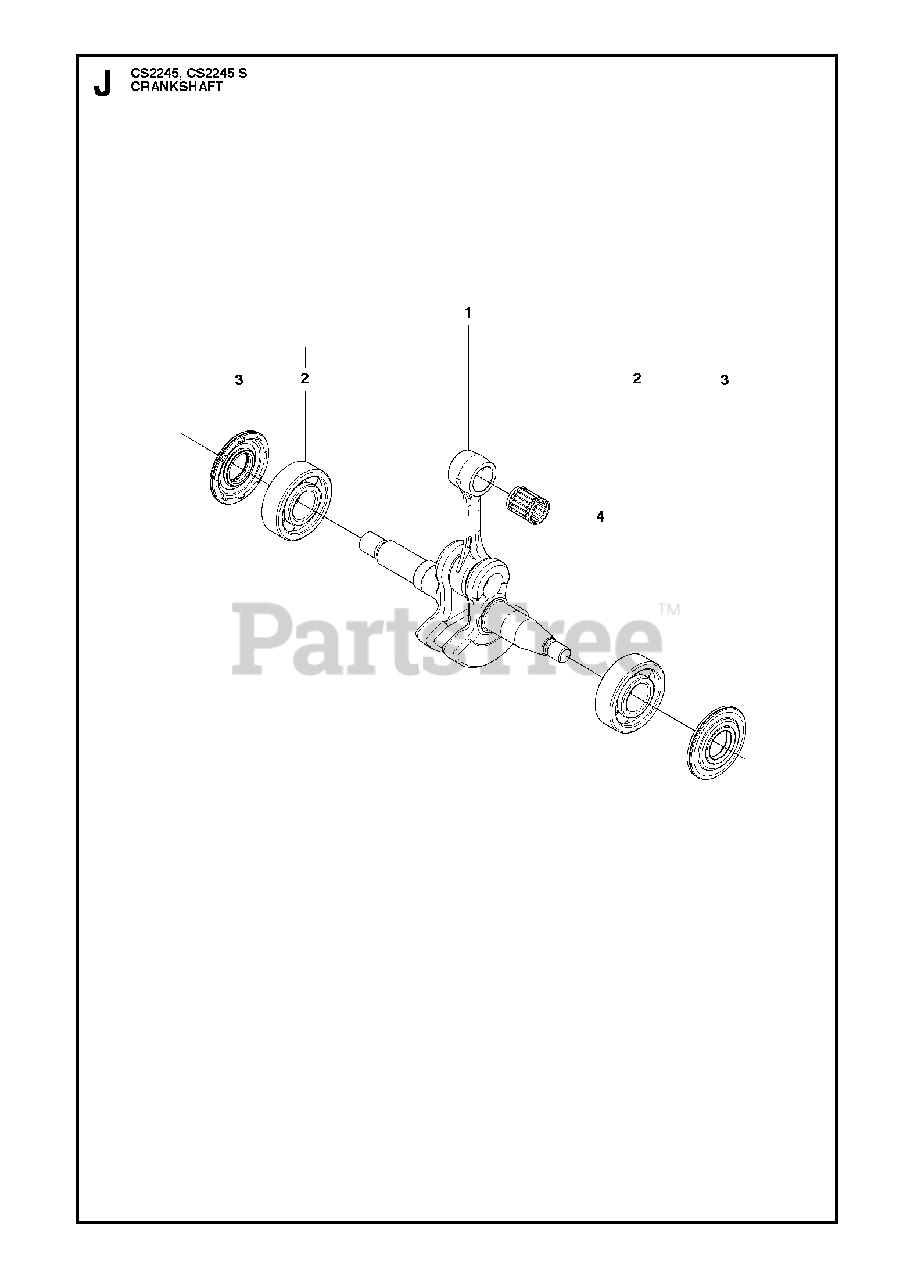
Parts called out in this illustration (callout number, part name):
1	CRANKSHAFT ASSY
2	BEARING
3	SEALING
4	NEEDLE BEARING
